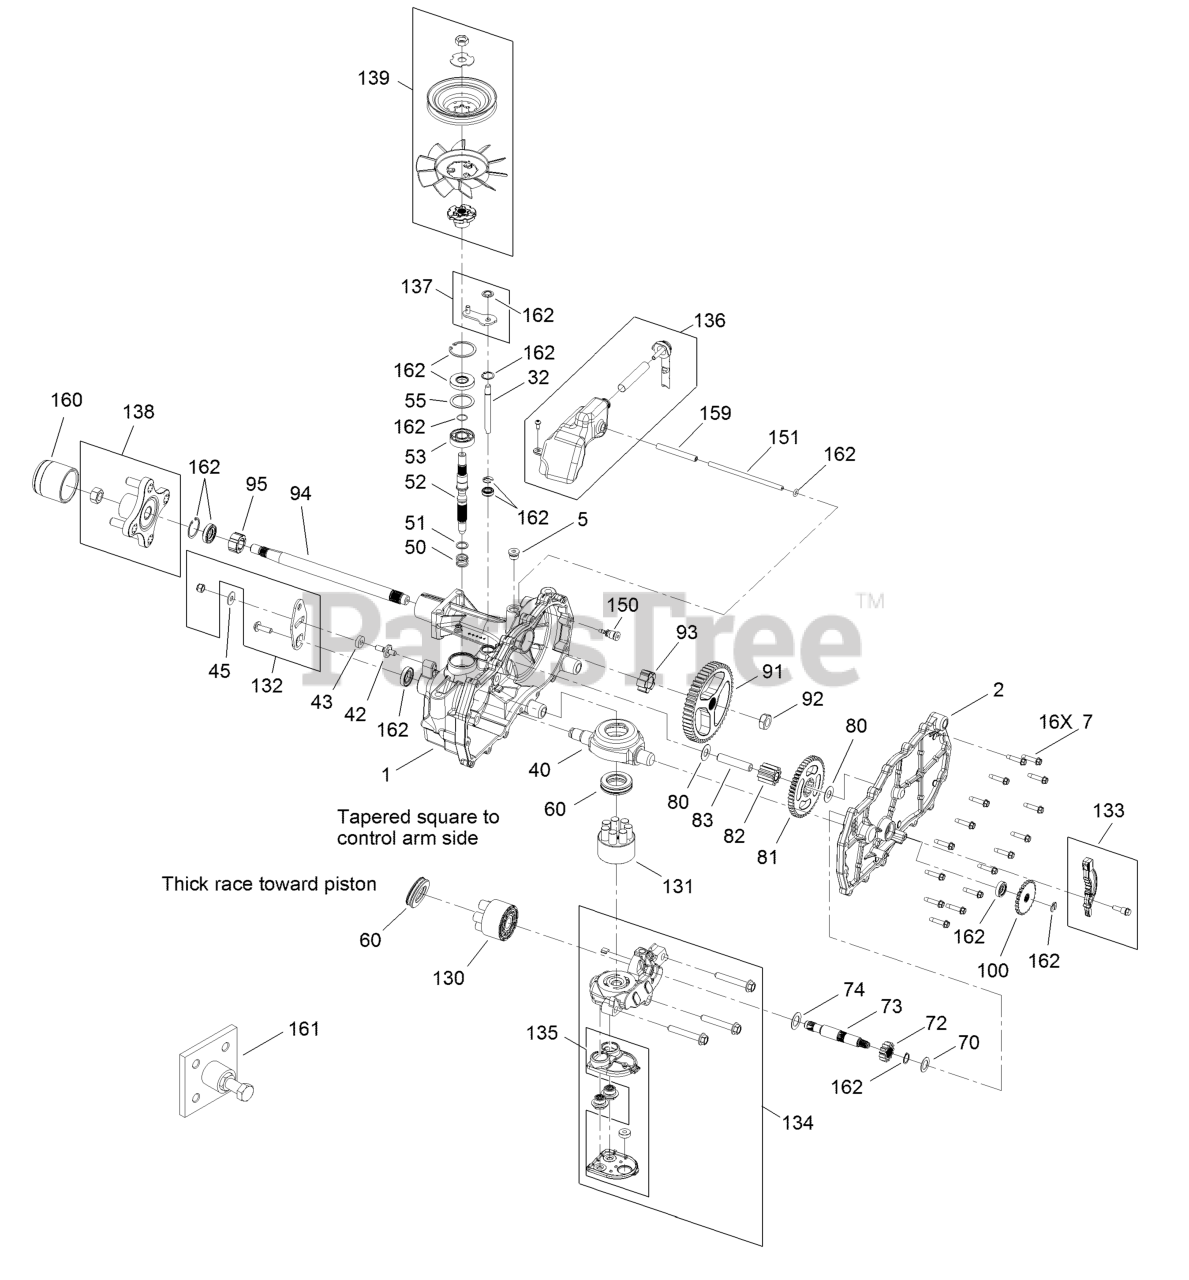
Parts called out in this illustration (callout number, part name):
1	Main Housing ASM
2	Housing Side Kit
5	Plug-Thread, Straight
7	Screw-HHF
13	Sealant
32	Rod-Bypass
40	Swashplate-Trunnion
43	Puck-Friction
50	Spring-Compression
52	Shaft-Input
53	Bearing-Ball
60	Bearing-Thrust
70	Washer-Flat
72	Gear-Pinnion, 13T
73	Shaft-Motor
80	Washer
81	Gear-10T/48T
82	Gear-Jackshaft, 10T
83	Pin-Jackshaft
91	Gear-Bull
93	Bushing-Inboard
94	Shaft-Axle
95	Bearing-Sleeve
100	Disc-Brake, Cog
130	Cylinder Block Kit
131	Pump Block ASM
132	Control Arm Kit
133	Brake Arm Kit
134	Center Section Filter Kit
135	Filter Kit
136	RH Expansion Tank Kit
137	Bypass Kit
138	Hub Kit
139	Fan Pulley Kit
150	Fitting-SAE
159	Case-Tube
160	Cap-Axle
161	Puller-Hub, 4 Bolt
162	Seal And Ring Kit
